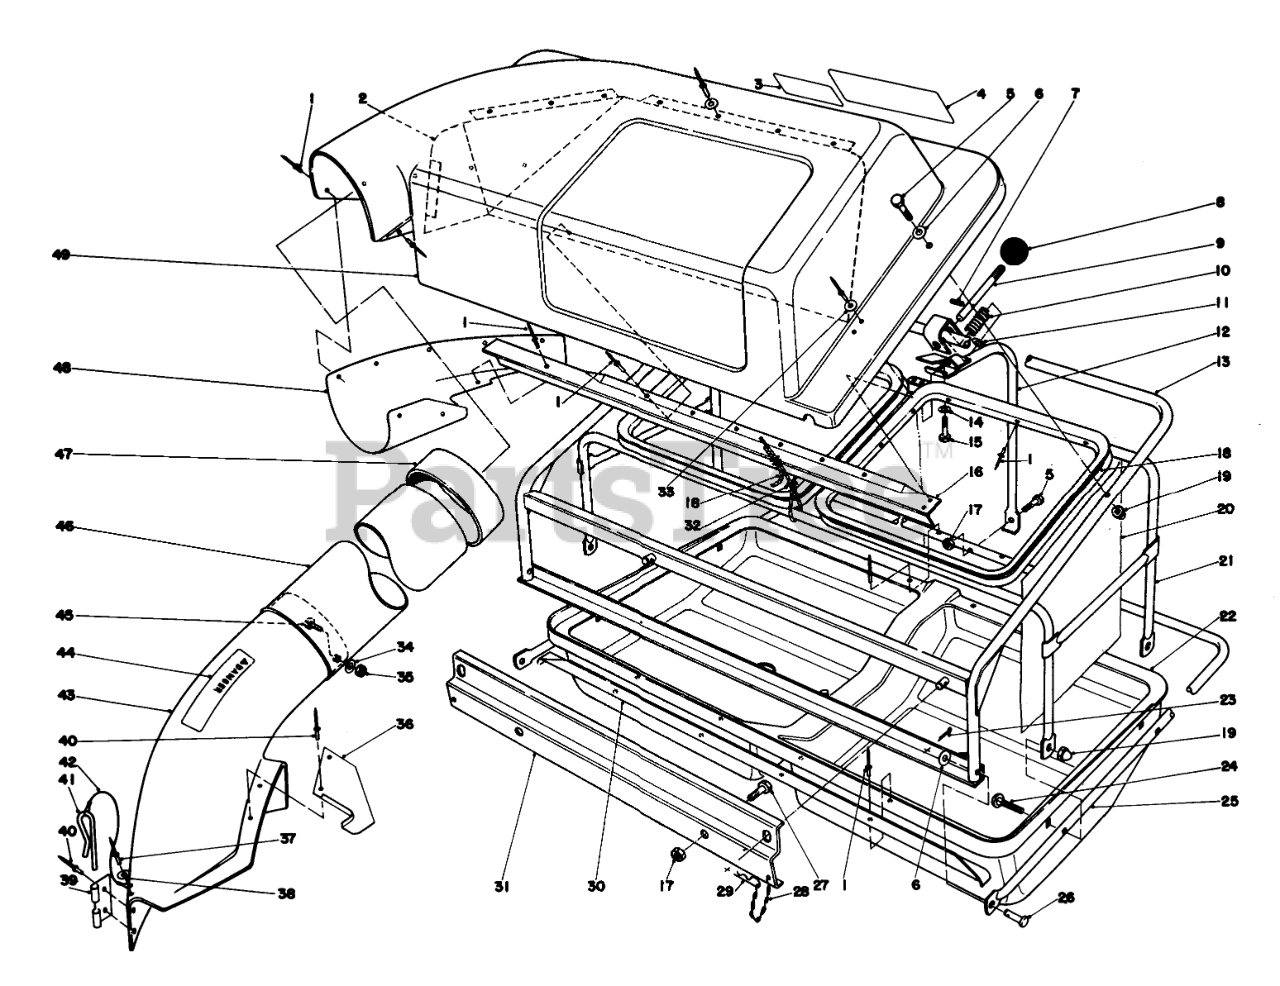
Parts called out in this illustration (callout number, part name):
2	Screen Cover
3	LATCH DECAL
4	EASY FILL DECAL
5	SCREW-HH
6	WASHER-PLAIN
7	PIN-ROLL, SLOT
9	Lever-Latch
10	Compression Spring
11	WASHER-FLAT
12	Handle Assembly
13	Frame Assembly
14	WASHER-LOCK
15	SCREW-HH
16	Bracket Screen Support
17	NUT-LOCK, CONE
18	RETAINER CORD
19	NUT-LOCK, CAP
20	Curtain
21	Bag Support Assembly
22	Hopper
23	PIN-COTTER
24	SCREW-CARR
25	HOPPER SUPT TUBE B
26	CLEVIS
27	SCREW-HH
28	6-LINK CHAIN W/HOOK
29	PIN-HAIR
30	HOPPER SUPT STRAPB
31	Bracket Frame Support
32	COUPLER
33	WASHER-FLAT
34	WASHER-FLAT
35	NUT-KEPS
36	CHUTE SUPT BRKT
37	RIVET-BLIND
38	WASHER-PLAIN
39	BRACKET-MOUNTING, CHUTE
40	RIVET-BLIND
41	PIN-LOCKING, CHUTE
42	LANYARD
43	Chute Assembly (Incl. Ref. #36-44)
44	Decal-Chute
45	BOLT-CARR
46	Duct
47	DUCT SEAL
48	Deflector
49	Cover
